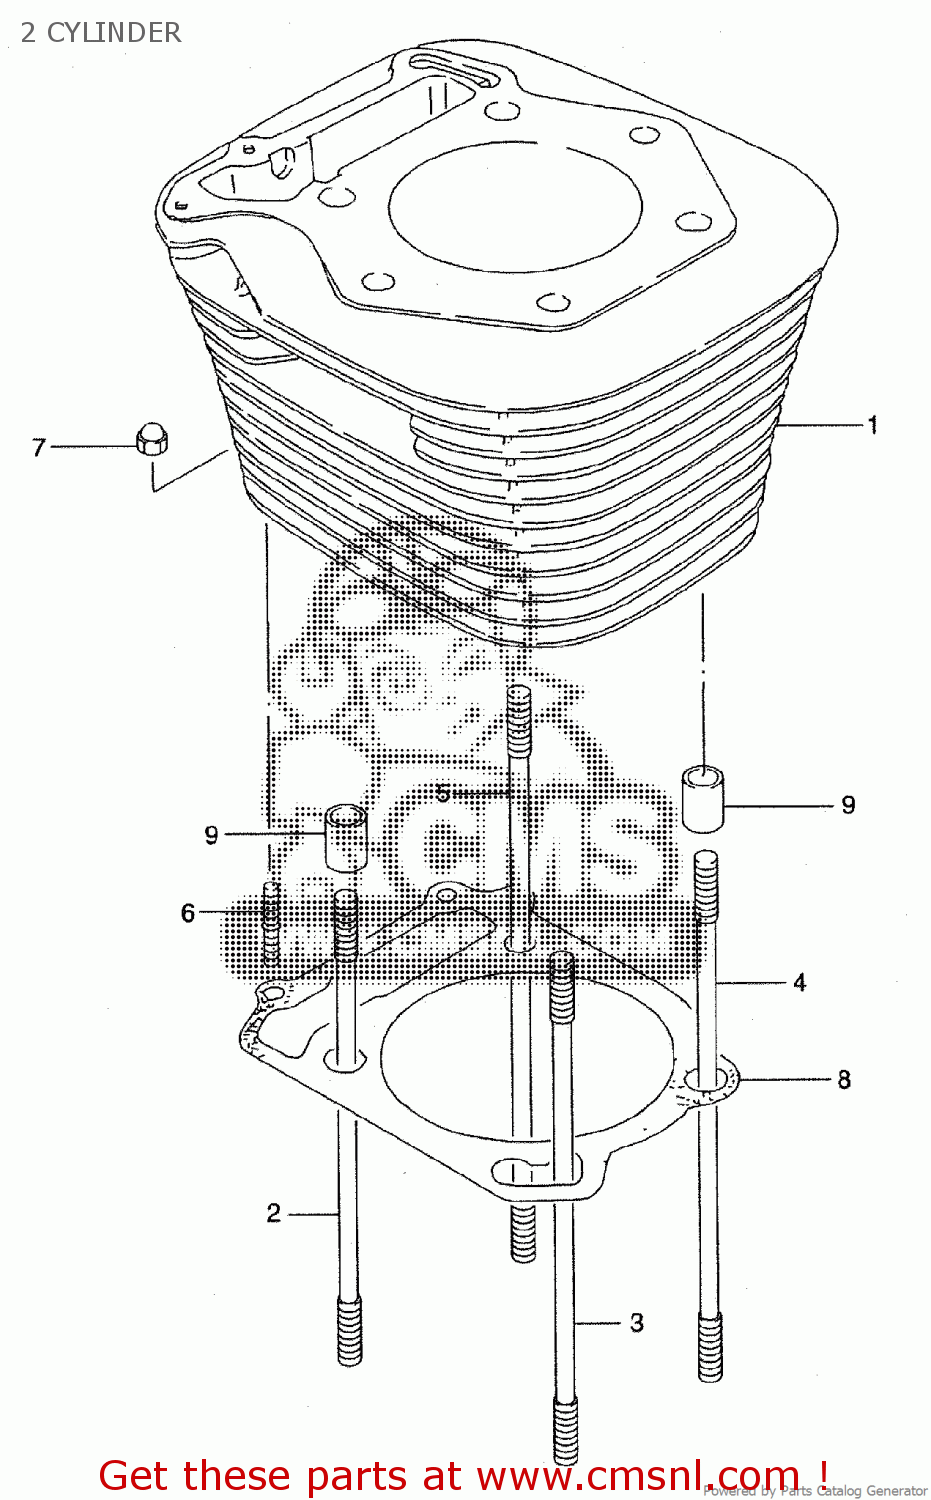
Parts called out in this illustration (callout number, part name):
2	BOLT,STUD
3	BOLT,STUD
4	BOLT,STUD
5	BOLT,STUD
6	STUD 6X20
7	NUT
8	GASKET,CYLINDER (NAS)
9	PIN
